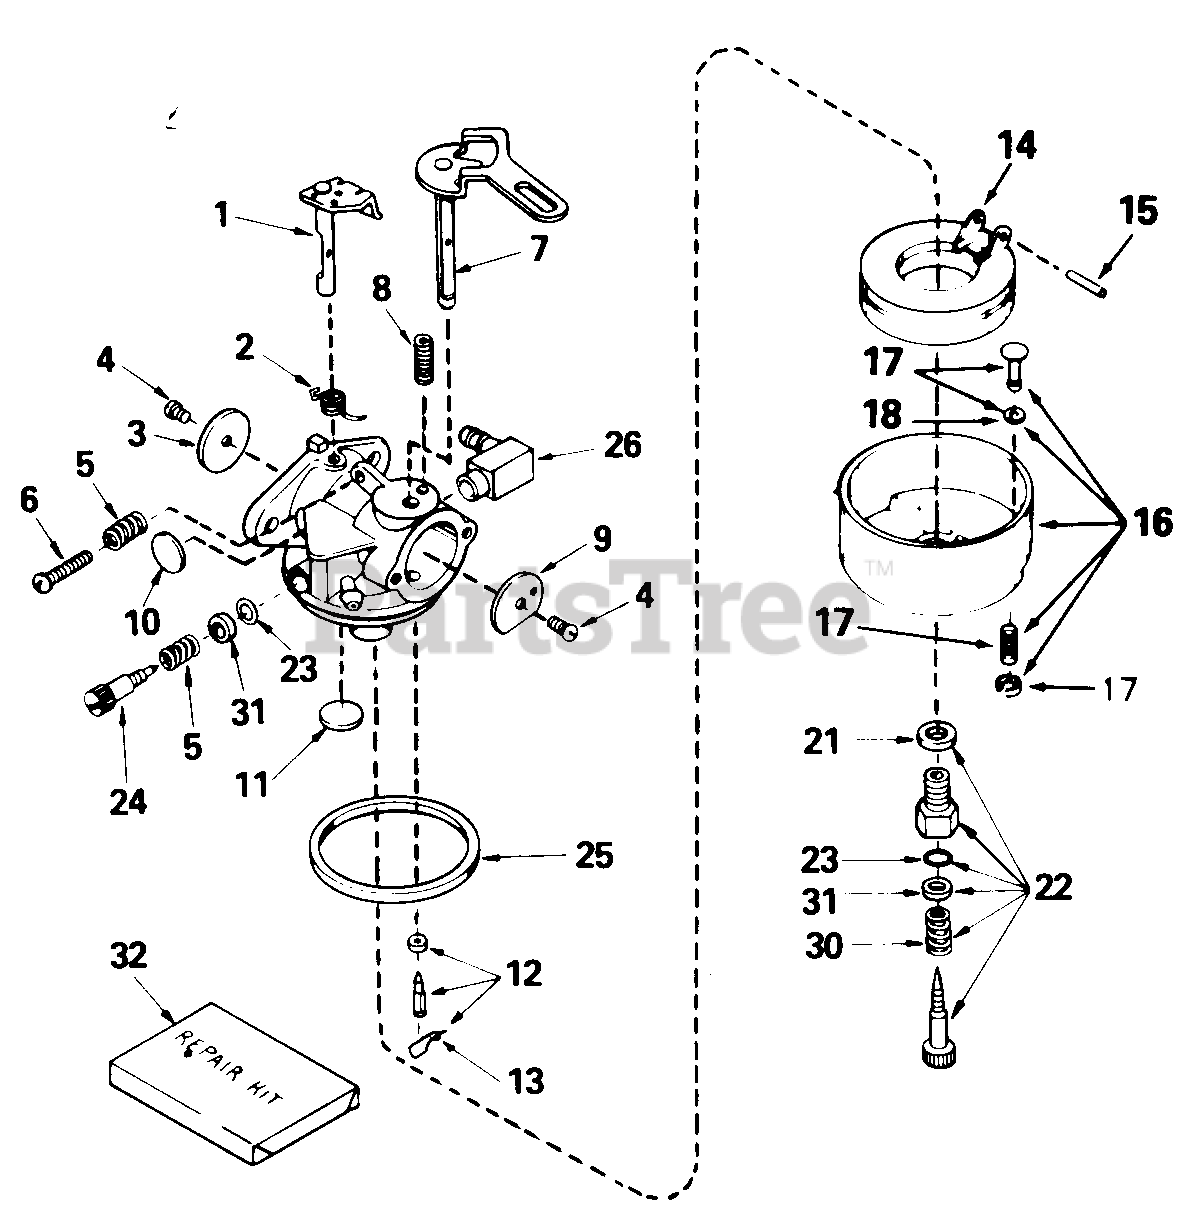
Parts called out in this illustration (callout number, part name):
1	Shaft & Lever Ass'y., Throttle
2	Spring, Throttle Return
3	Shutter, Throttle
4	Screw, 4-40 x 3/16
5	Spring, Idle Regulating Screw
6	Screw, Idle Regulating
7	Shaft & Lever Ass'y., Choke
8	Spring, Choke Stop
9	Shutter, Choke
10	Plug, Welch
11	Plug, Welch
12	Inlet Needle, Seat & Clip Ass'y.
13	Clip, Inlet Needle
14	Float, Carburetor
15	Shaft, Float
16	Bowl, Float
17	Drain Ass'y., Bowl
18	Gasket, Bowl Drain
21	Gasket, Bowl-to-Body
22	Adjustment Screw Ass'y., Main
23	"O"-Ring, Adjustment Screw
24	Screw, Idle Adjustment
25	Gasket, Bowl-to-Body
26	Fitting, Fuel Inlet
30	Spring, Main Adjustment Screw
31	Washer, Flat
32	Repair Kit
